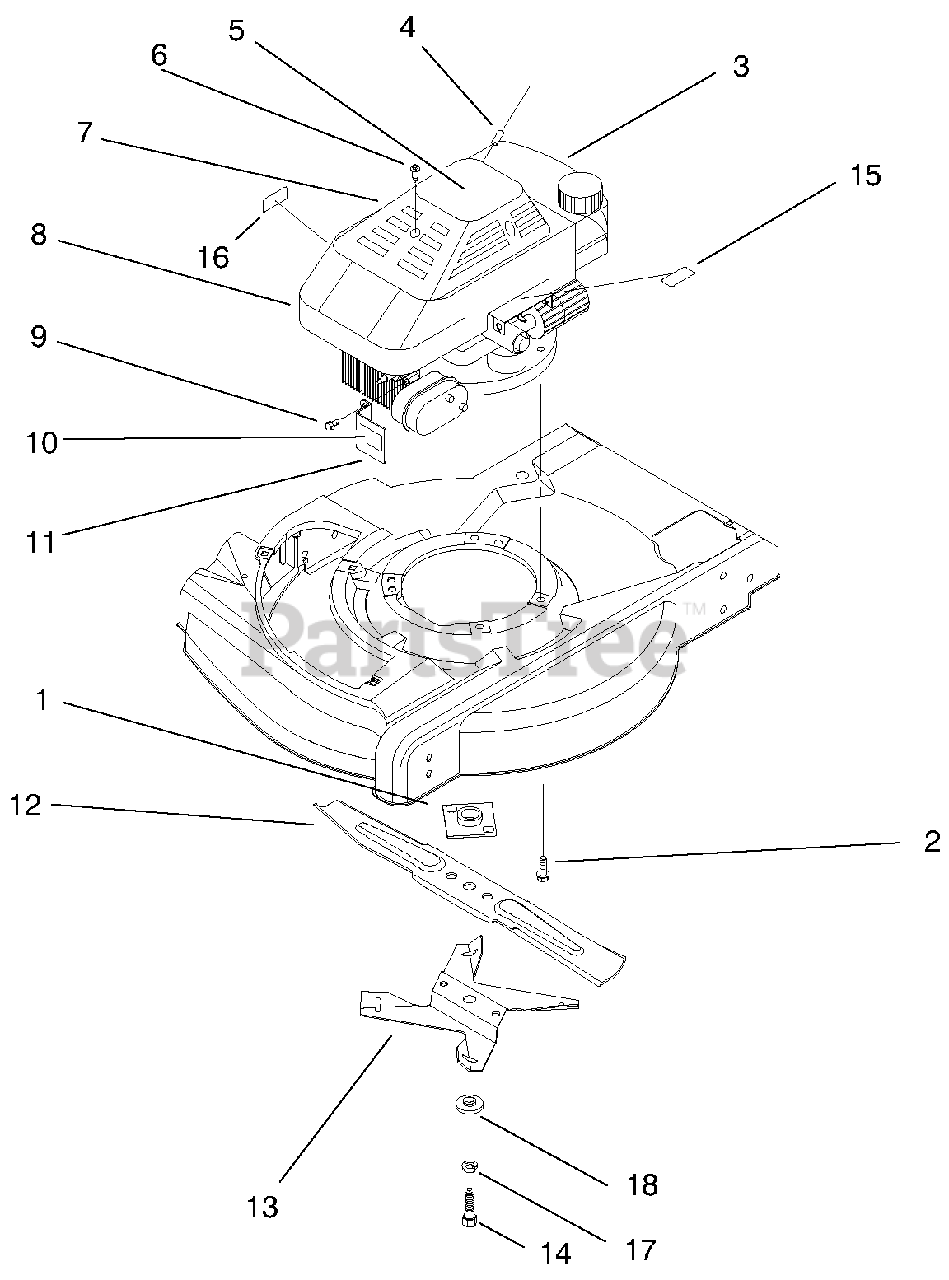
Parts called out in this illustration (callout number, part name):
1	ASM-Plate & Collar
2	Screw-Engine Mount
3	Engine ASM (4-Cyc)
4	Rope-Stop (P/W Eng)
5	Decal-Shroud Top
6	Screw-Recoil Cover
7	Cover-Starter
8	Shroud-Engine
9	Screw-HSH
10	Decal-Warning
11	Guard-Muffler
12	Blade-21" Whirl
13	Fan-Mulching
14	Bolt-Blade
15	Decal-Primer
16	Decal-Oil Instruction
